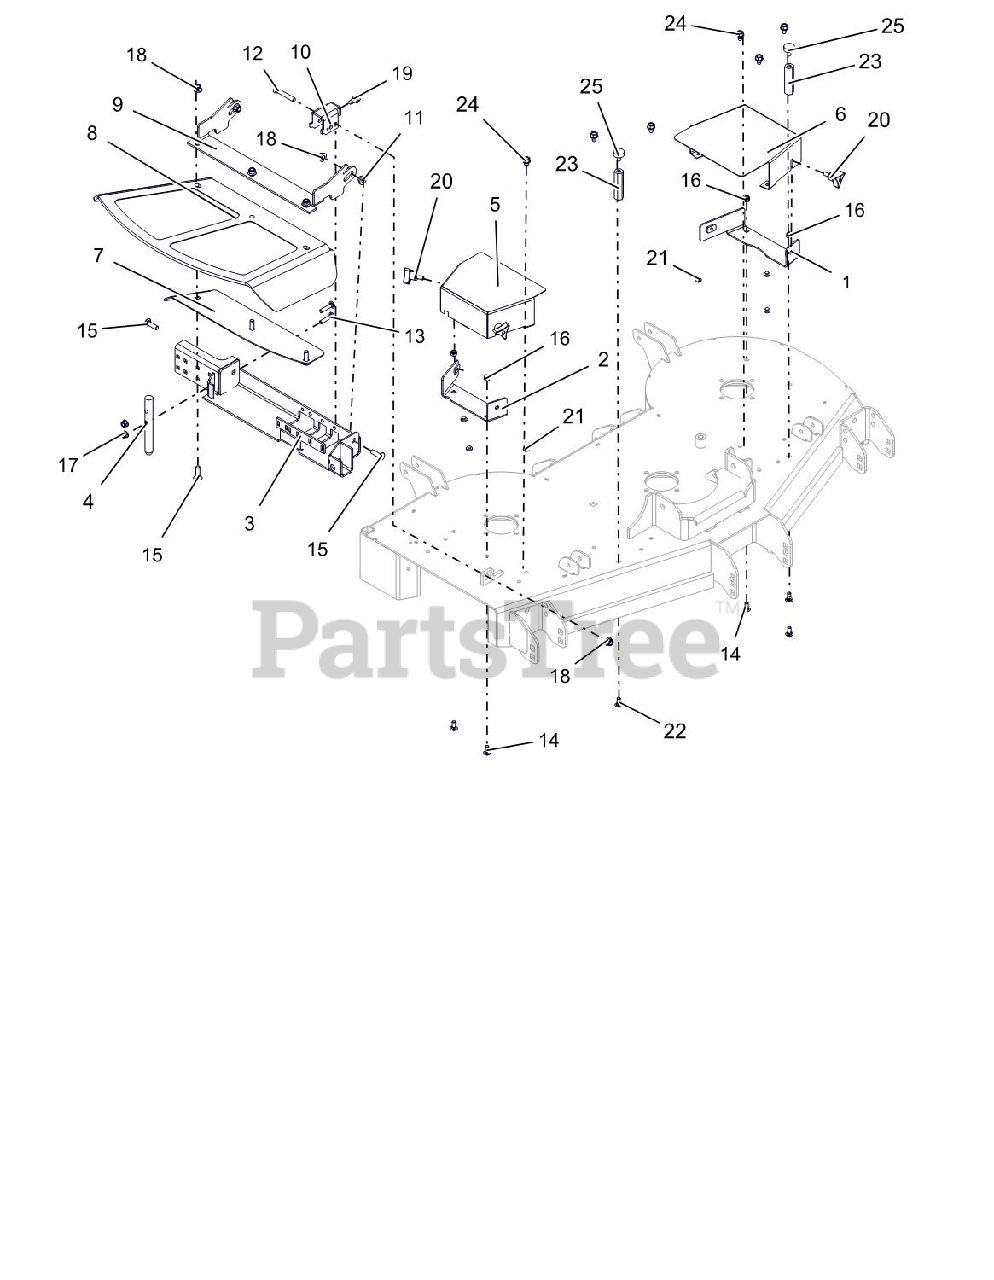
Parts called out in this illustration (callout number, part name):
1	BRKT, LH BELT GUARD MOUNTING
2	BRKT, RH BELT GUARD MOUNTING
3	WLDMT, GRASS CATCHER
4	PIN, DISCHARGE CHUTE X-DRILLED
5	GUARD, RH DECK BELT
6	GUARD, LH DECK BELT
7	48-60 DISCH CHUTE CLMP PLT-BLK
8	CHUTE,48-60" FRMD RUBBER DISCH
9	BRKT, 48-60" CHUTE MTG
10	BRKT, DISCH. CHUTE MTG
11	BSHG-FLG .385X.500X.875X.406
12	@BLT-HEX .38-16X2.25 GR5 YWZC
13	@BLT-RDHDSQNK .31-18X1.50 G5YZ
14	@BLT-RDHDSQNK .31-18X.75 G5YZ
15	@BLT-RHDSSQNK .38-16X1.25 G5YZ
16	@NUT-LK-NYL .312-18 YWZC
17	@NUT-LK-NYL-FLG .31-18 YWZC
18	@NUT-LK-NYL-FLG .38-16 YWZC
19	@SCR-TAP .38-16X.75 HWH TR YWZ
20	KNOB,WING STUD 5/16-18 X .75
21	BUMPER GROMMET
22	BLT,RDHDSQNK .31-18X.75 LOCTIT
23	NUT, COUPLING .31-18 X 3.00
24	@SCR-TAP .38-16X.50 HWH TR YWZ
25	BUMPER, RUBBER
